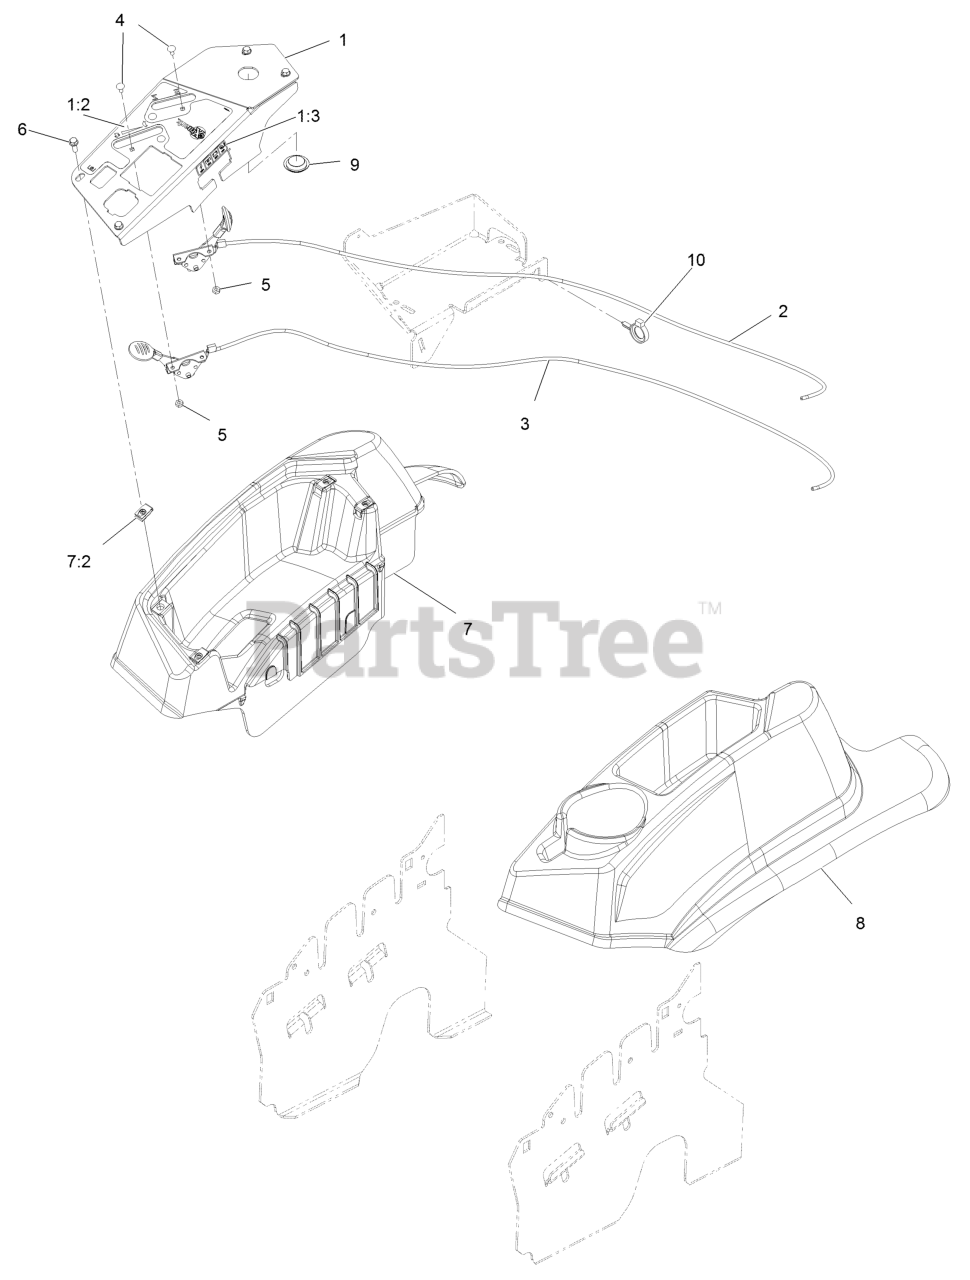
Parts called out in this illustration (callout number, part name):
1	CONSOLE,PANEL W/DECAL
1:2	DECAL-CONTROL PANEL NON-E
1:3	DECAL-FUSES
2	ASM, CHOKE CABLE
3	ASM,THROTTLE CABLE
4	BOLT-CARR
5	NUT-LOCK, NI
6	SCREW-HWH
7	CONSOLE,RH AS ASM
7:2	Nut-Retainer-Panel 1/4-20
8	CONSOLE, LH AS
9	PLUG-PLASTIC
10	CLAMP-HOSE
